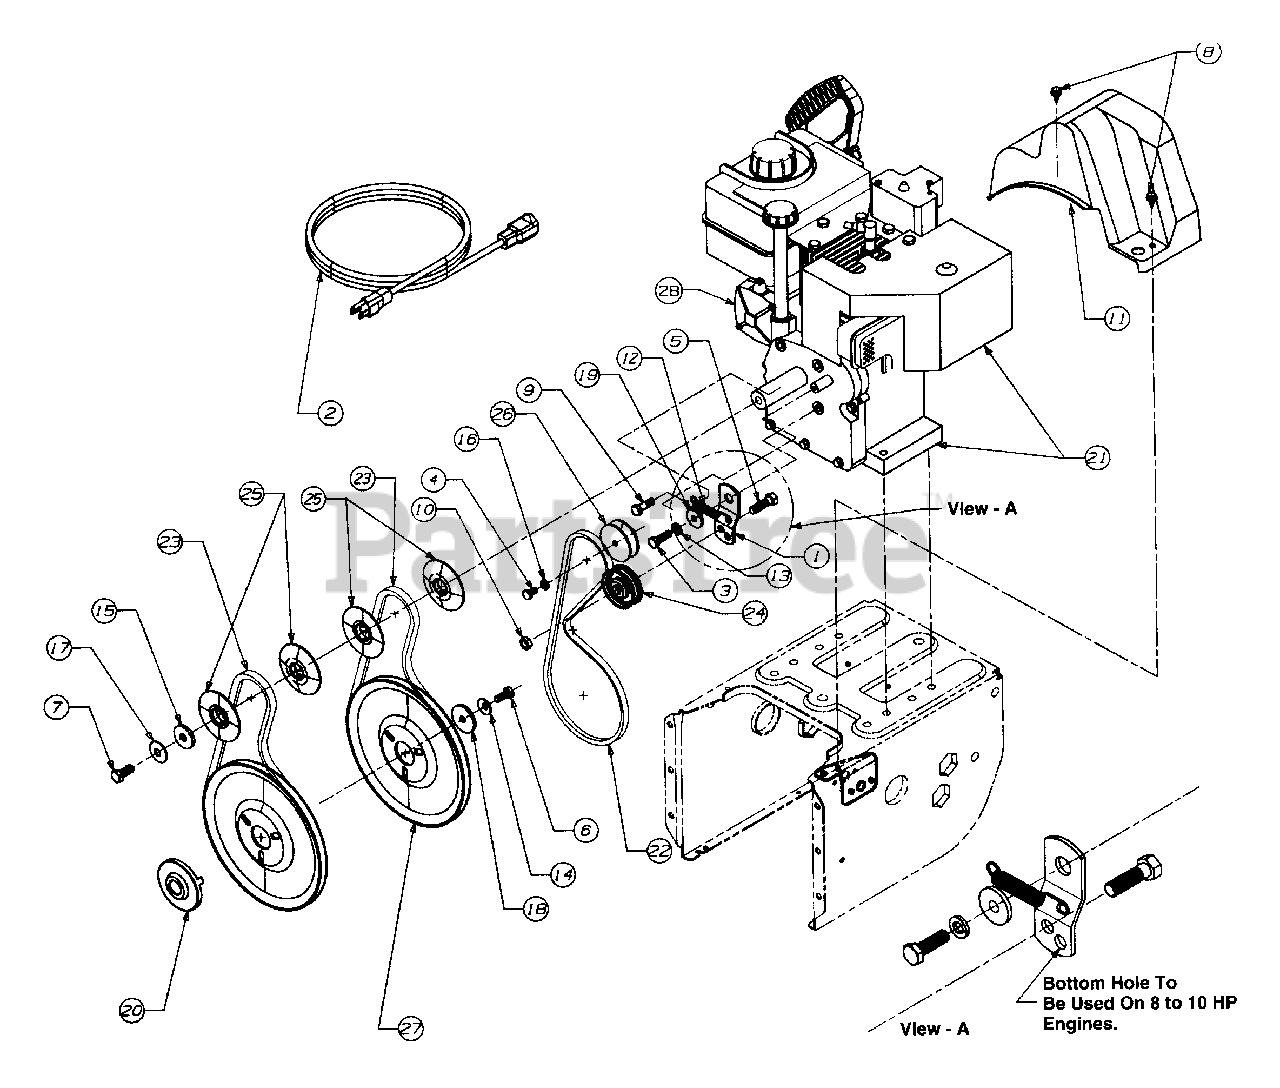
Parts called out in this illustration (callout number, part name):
3	Screw, Hex
4	Hex Screw
5	Screw, Hex
6	Screw, Hex
7	Screw, Hex
8	Hex Screw
9	Screw
10	Hex Jam Nut
11	Belt Cover
12	Spring
13	Lock Washer
14	Washer, Bell
15	Flat Washer
16	Washer, Lock
17	Washer, Bell
18	Washer, Flat
19	Shoulder Spacer
20	Pulley, Adapter
21	Eng., HMSK, Tec. 8 H.P., Horz.
21	Eng., HMSK, Tec. 10 HP, Horz.
22	V-Belt
23	V-Belt (Matched)
24	Idler, Flat
25	Pulley, Half
26	Pulley
27	Pulley, Auger
28	Electric Start Kit
